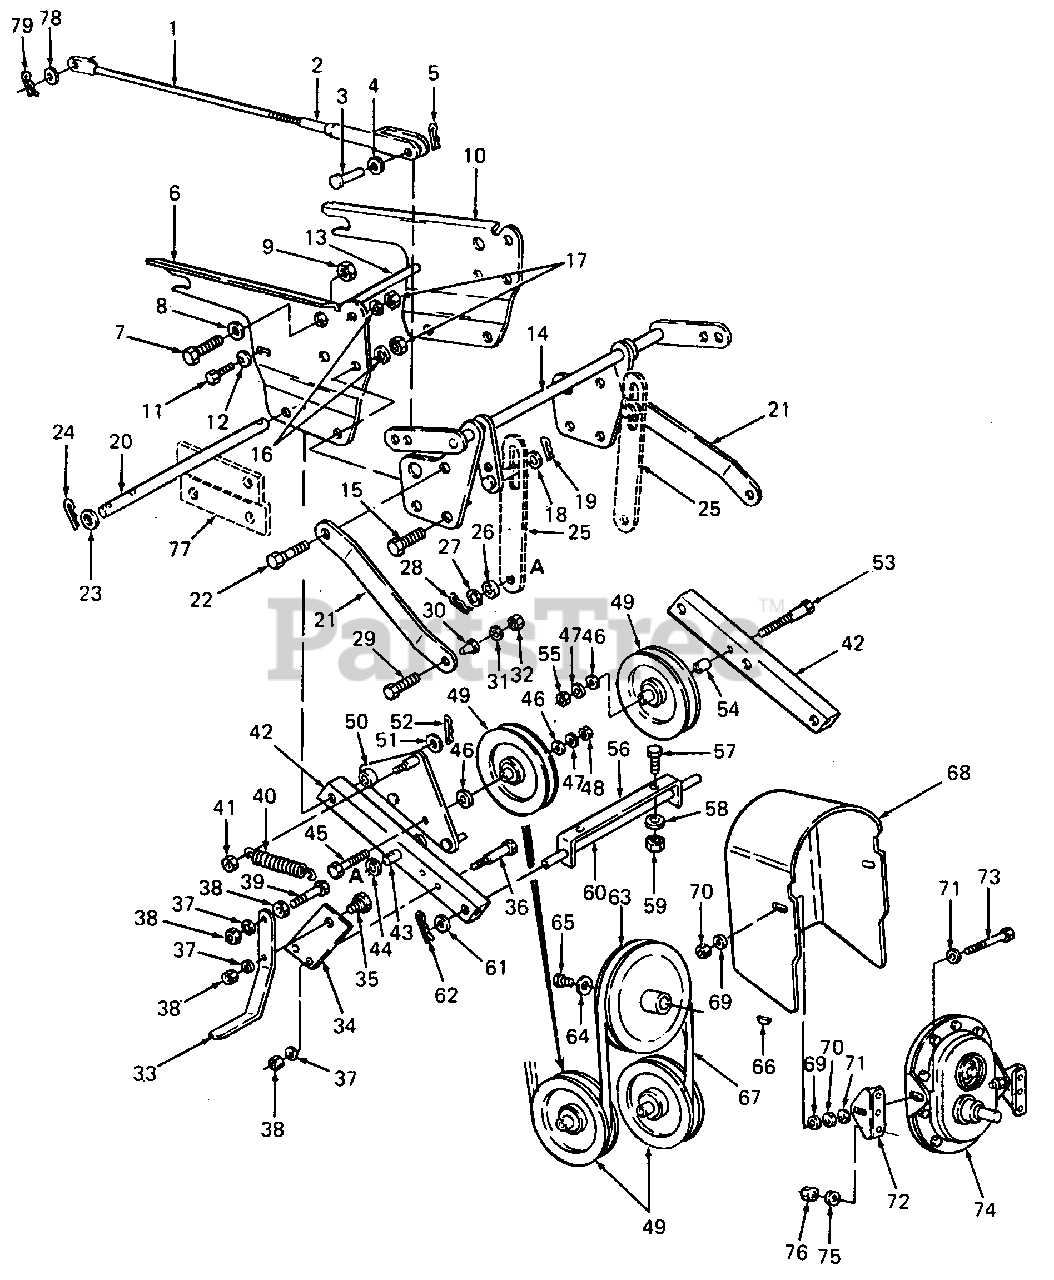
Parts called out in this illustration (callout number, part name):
1	Rod, Lift Handle, .75 Dia X 29.0 Lg
3	Pin, Clevis
4	Washer, Flat, .625 X 1.0 X .067 Thk
5	Pin, Hitch Clip
6	Carriage Brkt - RH
7	Screw, Hex Cap, 1/2-13 X 1.25 Lg GR5
8	Washer, Belleville, .505 X 1.0 X .075 Thk
9	Nut, Pilot Weld, 1/2-13
10	Carriage Brkt - LH
11	Screw, Hex Cap, 5/16-24 X 1.0 Lg
12	Washer, Belleville, .345 X .88 X .060 Thk
13	Rod, Carriage Brkt, Support
14	Pivot Assy
15	Screw, Hex Cap, 1/2-20 X 1.25 Lg
16	Washer, Lock, 1/2
17	Nut, Hex Jam, 1/2-20
18	Washer, Flat, .625 X 1.0 X .067 Thk
19	Pin, Hitch Clip
20	Rod, 12.5 Lg
21	Pivot Link, 15.5 Lg
22	Bolt, Shoulder, .625 Dia X .36 Lg
23	Washer, Flat, .625 X 1.0 X .067 Thk
24	Pin, Hitch Clip
25	Lift Link, 10.2 Lg
26	Spacer, .635 X .885 X .33 Lg
27	Washer, Flat, .625 X 1.0 X .067 Thk
28	Pin, Hitch Clip
29	Screw, Hex Cap, 3/8-24 X 1.25 Lg GR5
30	Spacer, Shoulder, .38 ID
31	Washer, Lock, 3/8
32	Nut, Hex Insert Lock, 3/8-24
35	Bolt, Shoulder, .625 Dia X .217 Lg
36	Screw, Hex Cap, 3/8-16 X 3.0 Lg
37	Washer, Lock, 3/8
38	Nut, Hex, 3/8-16
39	Screw, Hex Cap, 3/8-16 X 2.25 Lg
40	Spring, Extension
41	Nut, Hex Insert Lock, 3/8-24
42	Tubing, Square
43	Pin, Clevis
44	Washer, Flat, .625 X 1.0 X .067 Thk
45	Screw, Hex Cap, 1/2-13 X 2.0 Lg
46	Washer, Flat, .510 X 1.0 X .12 Thk
47	Washer, Lock, 1/2
48	Nut, Hex, 1/2-13
49	Pulley, Idler, .50 ID X 6.0 OD
52	Pin, Hitch Clip
53	Screw, Hex Cap, 1/2-20 X 4.5 Lg GR5
54	Spacer, .50 X .75 X .780 Lg
55	Nut, Hex,1/2-20
56	Pivot Brkt, Blower Hsg
57	Screw, Hex Cap, 1/2-20 X 1.25 Lg
58	Washer, Lock, 1/2
59	Nut, Hex Jam, 1/2-20
60	Rod, 12.5 Lg
61	Washer, Flat, .625 X 1.0 X .067 Thk
62	Pin, Hitch Clip
65	Screw, Hex Patch, 3/8-24 X 1.0 Lg GR5
66	Key, Hi-Pro, 1/4 X 3/4
67	Belt, 5/8 X 84.0 Lg
68	Cover, Belt
69	Washer, Flat, .344 X .88 X .063 Thk
70	Nut, Hex, 5/16-18
71	Washer, Belleville, .345 X .88 X .060 Thk
72	Bracket, Gear Box Support
73	Screw, Hex Cap, 5/16-18 X 1.25 Lg GR5
74	Gear Box Assy
75	Washer, Lock, 1/4
76	Nut, Hex, 1/4-28
79	Washer, Lock, 1/2
